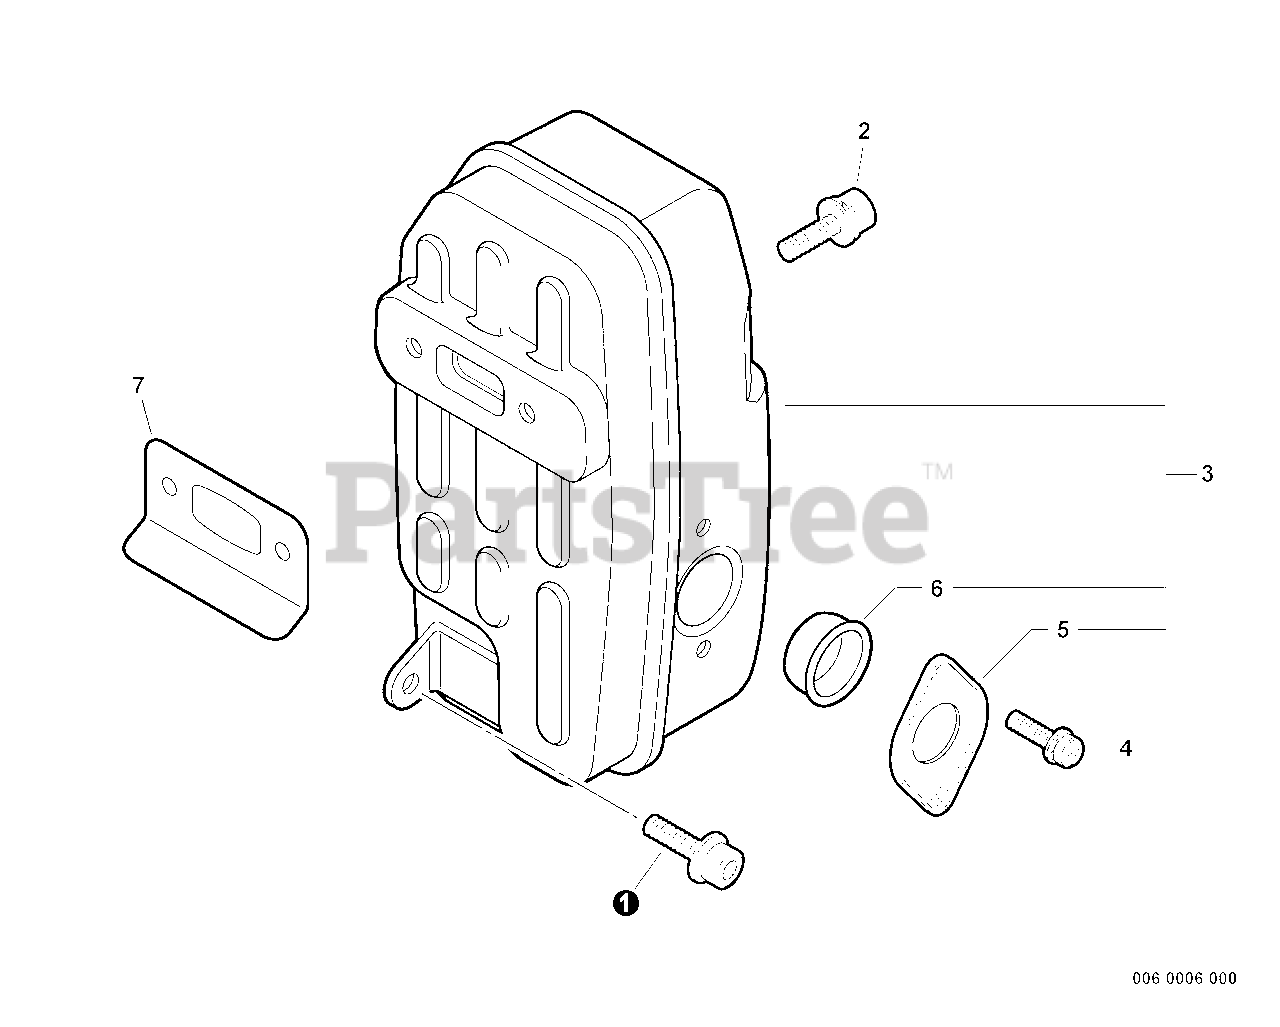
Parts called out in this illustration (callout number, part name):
1	SCREW - 5X14
2	SCREW - 6X20
3	MUFFLER ASSY
4	SCREW - 4X12
5	GUIDE, EXHAUST
6	SCREEN, SPARK ARRESTOR
7	GASKET, EXHAUST
